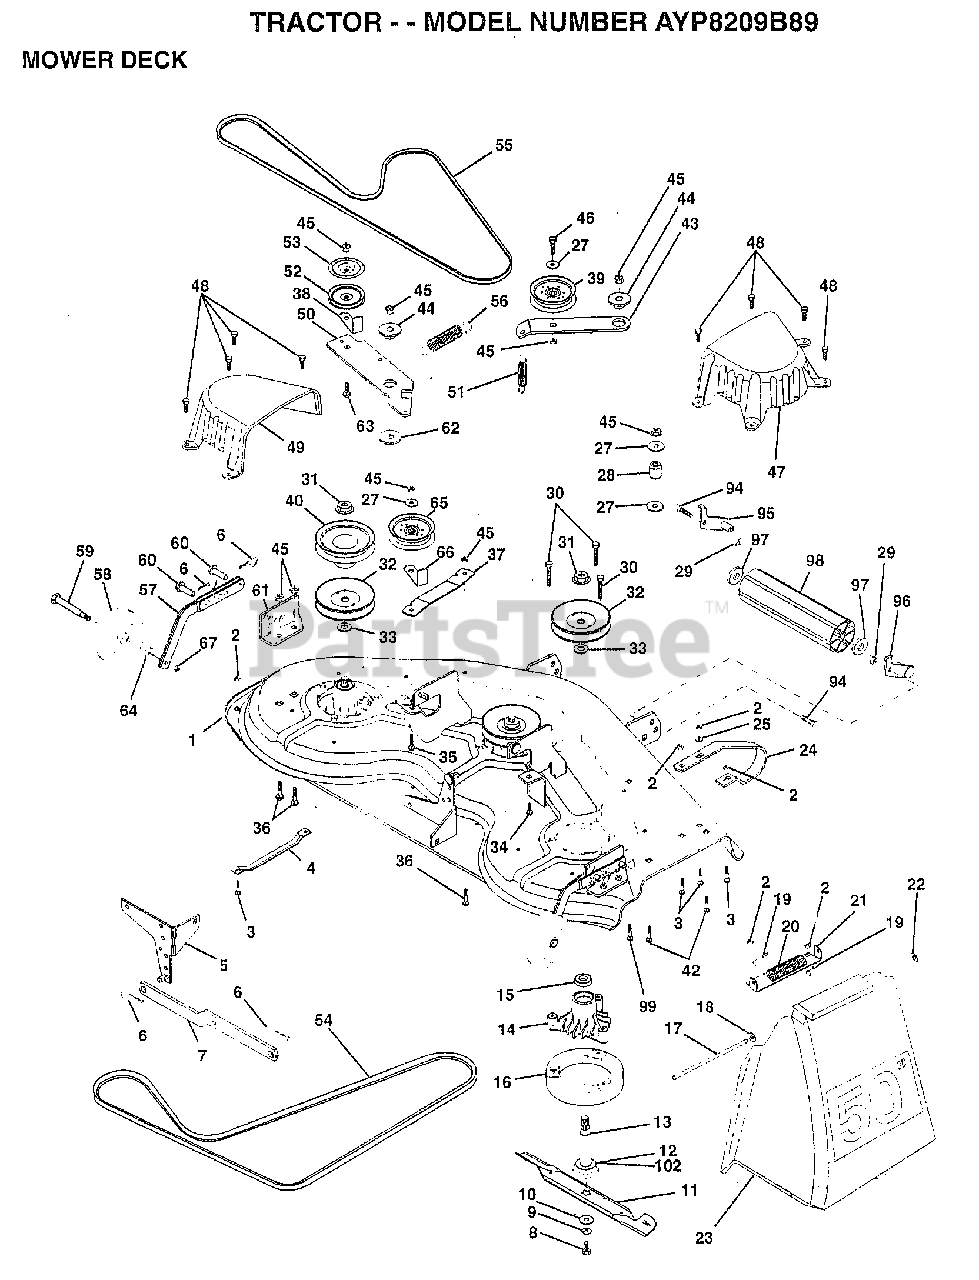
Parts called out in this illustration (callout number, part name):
1	"DECK ASM-50"""
4	RUNNER-LH M
5	BRKT.ASM.SW.44/50
8	BLADE BOLT
10	WASHER.HARD.BLADE
11	"BLADE.50"" HD"
12	BEARING.BALL
13	SHAFT.ASM.W/BRNG
14	HOUSING.MAND.44.V
15	BEARING
16	STRIPPER RND MWR
17	ROD-HINGE T
18	WASHER
20	SPRING TORSION
21	BRKT DEFLECTOR
23	DEFLECTOR
24	"RUNNER RH 50"" DK"
25	WASHER M
27	WASHER
29	NUT
30	"SCREW-THD ROLL,WA"
32	PULLEY.MANDREL.42
33	WASHER
34	BOLT.3/8-14X1.25
35	BOLT
36	BOLT D
37	STIFFENER.ARM.IDL
38	"KEEPER-BELT,IDLER"
39	FLAT IDLER PULLEY
40	"PULLEY.DRIVEN.44"""
42	BOLT
43	"ARM.IDLER.SEC.44"""
44	SPACER RETAINER
47	"COVER.MAND.RH.44"""
48	SCREW.1/4-20X5/8
49	COVER.MANDREL.LH
50	ARM.IDLER.PRIMARY
51	"SPRING.SEC.44""VEN"
52	PULLEY.IDLER.VGRO
53	SHIELD.IDLER.44.V
54	BELT V PRIM 50
55	BELT-V.SEC.46.KEL
56	SPRING.EXT.DECK.
57	BAR.ASM.GUAGE.WHL
58	WHEEL GAGE DONUT
59	BOLT.SHOULDER
60	PIN.CLEVIS
61	BRACKET.GUAGE.WHL
62	HARDENED WASHER
63	BOLT.3/8-16X1.50
64	WASHER
65	PULLEY IDELR FLAT
66	"KEEPER-BELT,IDLER"
67	LOCKNUT
94	BOLT
97	WASHER
99	BOLT
102	WASHER.FELT.
